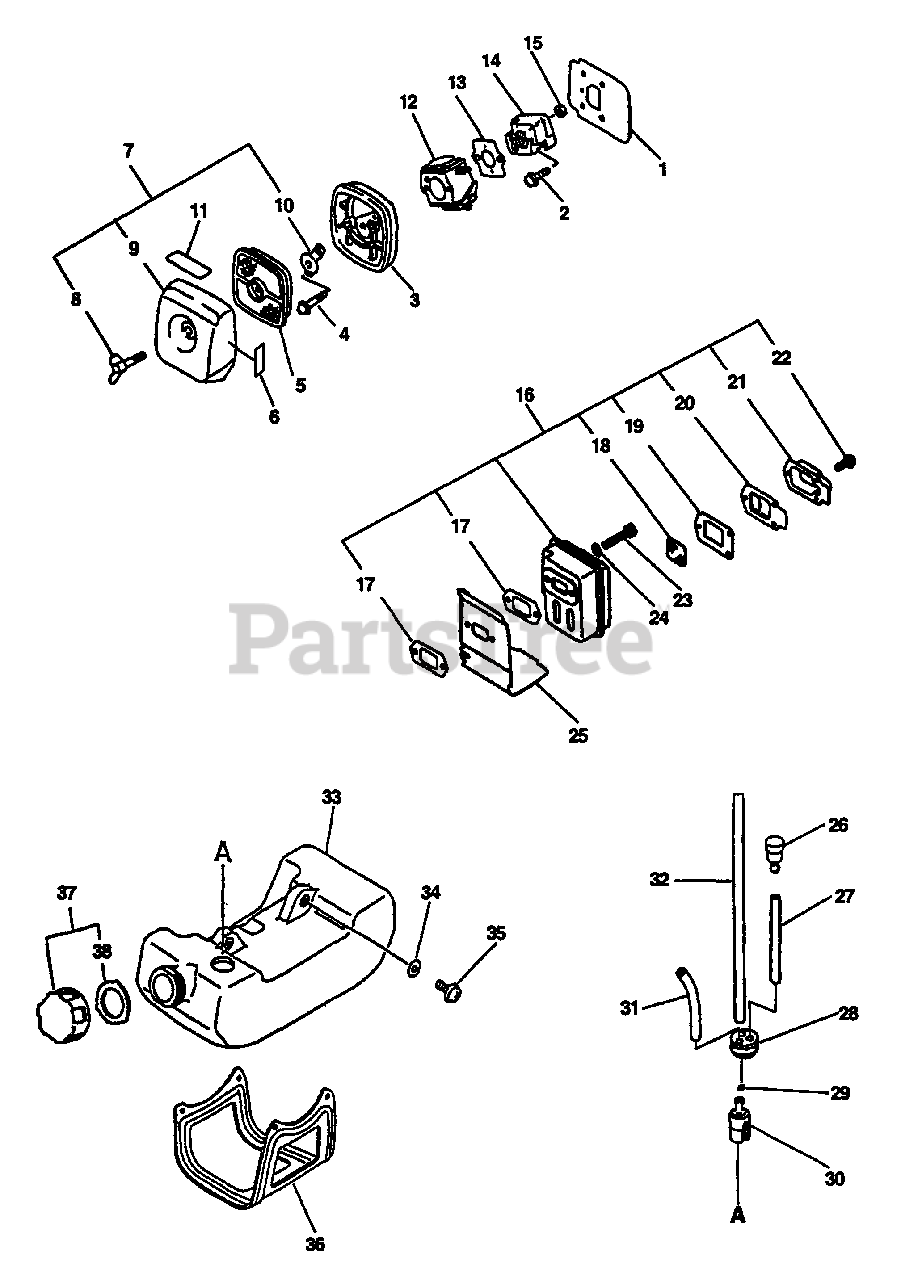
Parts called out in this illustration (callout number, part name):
1	HEAT SHIELD, INTAKE
2	SCREW 5×20
3	AIR FILTER CASE ASSY
4	SCREW 5×65
5	FILTER, AIR - SINGLE LAYER
6	LABEL, CHOKE
7	COVER, AIR FILTER
8	BOLT, WING 5×20
9	COVER, AIR FILTER - GRAY
10	PLATE, PREVENT
11	LABEL - METERING
12	CARBURETOR - WT-424A
13	GASKET, CARBURETOR
14	INSULATOR, INTAKE
15	NUT M5
16	MUFFLER ASSY
17	GASKET, EXHAUST
18	SCREEN, SPARK ARRESTER
19	GASKET, EXHAUST
20	GUIDE, EXHAUST
21	OUTLET, EXHAUST
22	SCREW 4×10
23	BOLT 5×55
24	WASHER, FLAT 5.5×10×0.8
25	COVER, EXHAUST
26	VENT ASSY
27	PIPE, FUEL 3x-5x-70 BLACK
28	GROMMET, FUEL
29	CLIP 6 MM
30	FILTER, FUEL
31	PIPE, FUEL 3×6×80 CLEAR
32	PIPE, FUEL 3x-5x-180
33	TANK, FUEL
34	WASHER 5.5×12×0.8
35	SCREW 5×16
36	GUARD, FUEL TANK
37	CAP ASSY, FUEL
38	GASKET, FUEL CAP
